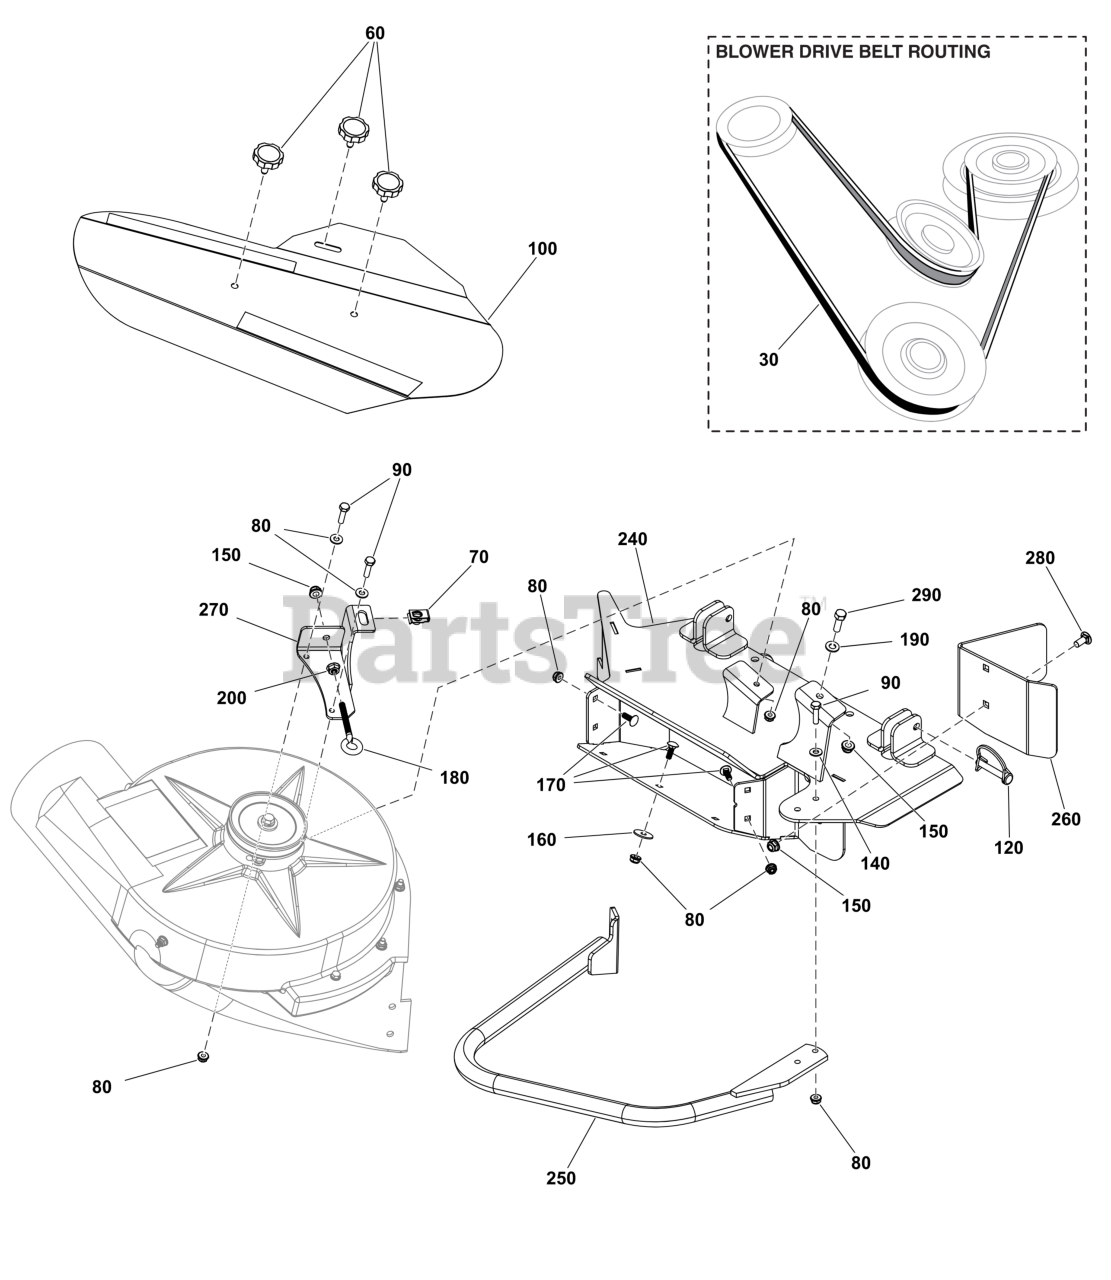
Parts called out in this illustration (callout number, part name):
60	KNOB, 5/616-18 X 1
70	NUT, SPEED, 5/16-18 L
90	BOLT, 1/4-20 X 1", GD
100	HOOD ASSEMBLY
120	SNAPPERPIN
140	WASHER
150	NUT
160	WASHER, 1/4 FENDER
170	BOLT, 1/4-20X.750, SQ
180	EYE BOLT, 5/16-18 X 3
190	WASHER
200	NUT, 5/16-18 HEX SERR
240	ADAPTER
260	PLATE, Baffle
270	WELD, SPRING ANCHOR, 61 TP - BLK
280	BOLT, 5/16-18 X 3/4",
